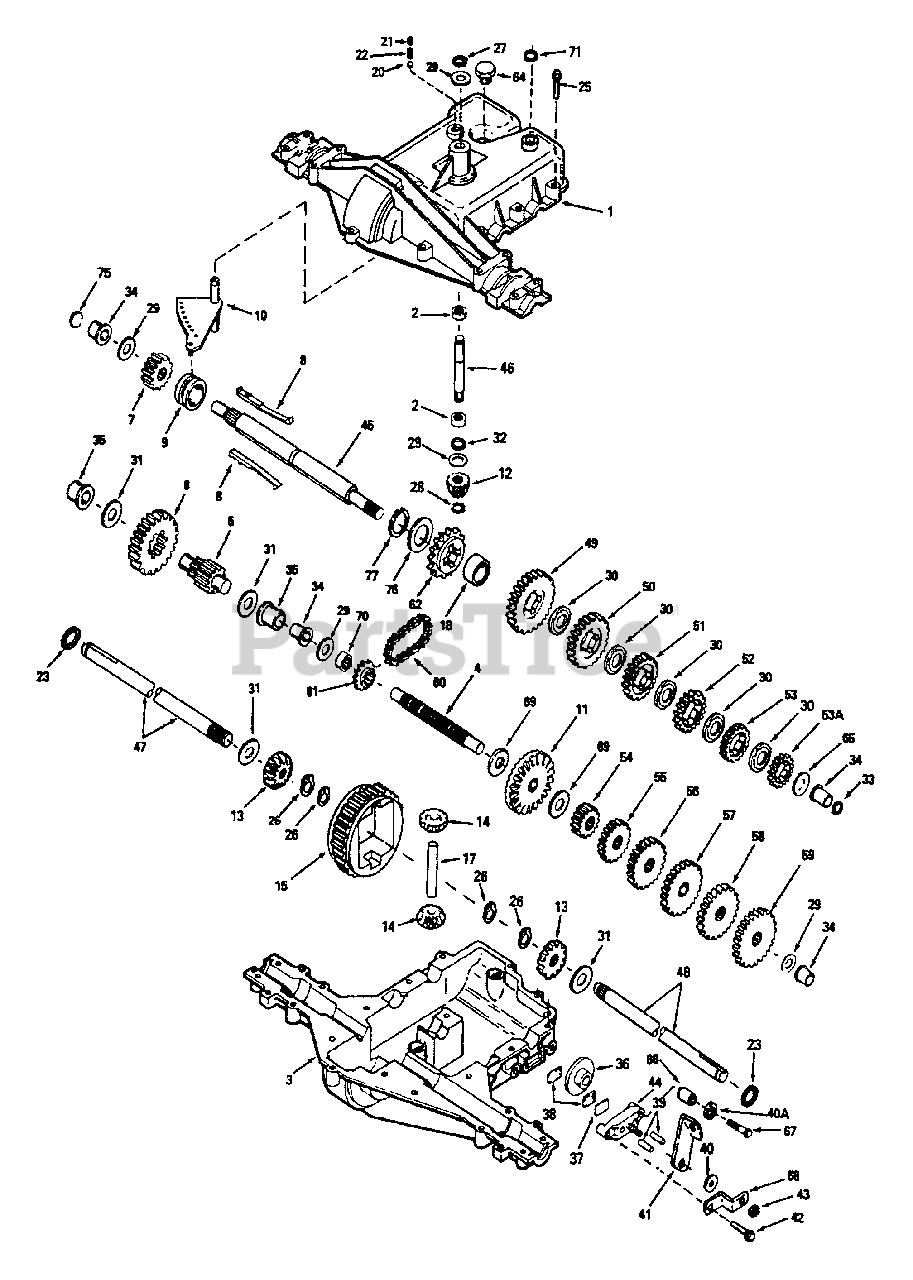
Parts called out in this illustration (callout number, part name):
1	Cover, Transaxle
2	Bearing, Needle
3	Case, Transaxle
4	Shaft, Counter
5	Shaft and Pinion Assembly, Output
6	Gear, Output
7	Gear Spur 15 Teeth
9	Collar, Shifter
10	Rod & Fork Assembly, Shift
11	Gear, Bevel 42 Teeth
12	Bevel Pinion, Input
13	Gear, Bevel
14	Gear, Bevel Pinion
15	Gear, Ring
17	Pin, Drive
18	Spacer, Neutral
20	Ball, Steel 5/16° diameter
21	Set Screw 3/8-16 x 3/8
23	Ring, Felt
25	Screw, Flanged Hex Head, Thread Forming 1/4-20 x 1-1/4
26	Ring, Retainer
27	Ring, Retainer
28	Ring, Retainer
29	Washer, Thrust
30	Washer, Thrust
32	"O" Ring
33	Seal, Square Cut
34	Bushing, Flanged
35	Bushing, Flanged
36	Disk, Brake
37	Plate, Brake Pad
38	Pad, Brake
39	Pin, Dowel
40	Washer, Flat
40A	Washer, Flat
41	Lever, Brake
42	Screw, Flanged Hex Head, Thread Forming 1/4-20 x 1-1/4
43	Locknut 5/16-24
44	Holder, Brake Pad
45	Shaft, Brake, 4-Keyed
46	Shaft, Input
47	Axle, 11-15/16"
48	Axle, 16-1/2"
49	Gear, Spur 37 Teeth
50	Gear, Spur 35 Teeth
51	Gear, Spur 30 Teeth
52	Gear, Spur 25 Teeth
53	Gear, Spur 22 Teeth
53A	Gear, Spur 19 Teeth
54	Gear, Spur 12 Teeth
55	Gear, Spur 15 Teeth
56	Gear, Spur 20 Teeth
57	Gear, Spur 25 Teeth
58	Gear, Spur 28 Teeth
59	Gear, Spur 31 Teeth
60	Chain, Roller
61	Sprocket 9 Teeth
62	Sprocket 18 Teeth
64	Plug, Hex Head, Threaded 9/16-18
65	Washer, Thrust
67	Screw, Flanged Hex Head, Thread Forming 1/4-20 x 2-1/4
68	Bracket, Brake Lever
69	Washer, Thrust
71	Seal, Square Cut
76	Washer, Thrust
77	Ring, Retaining
